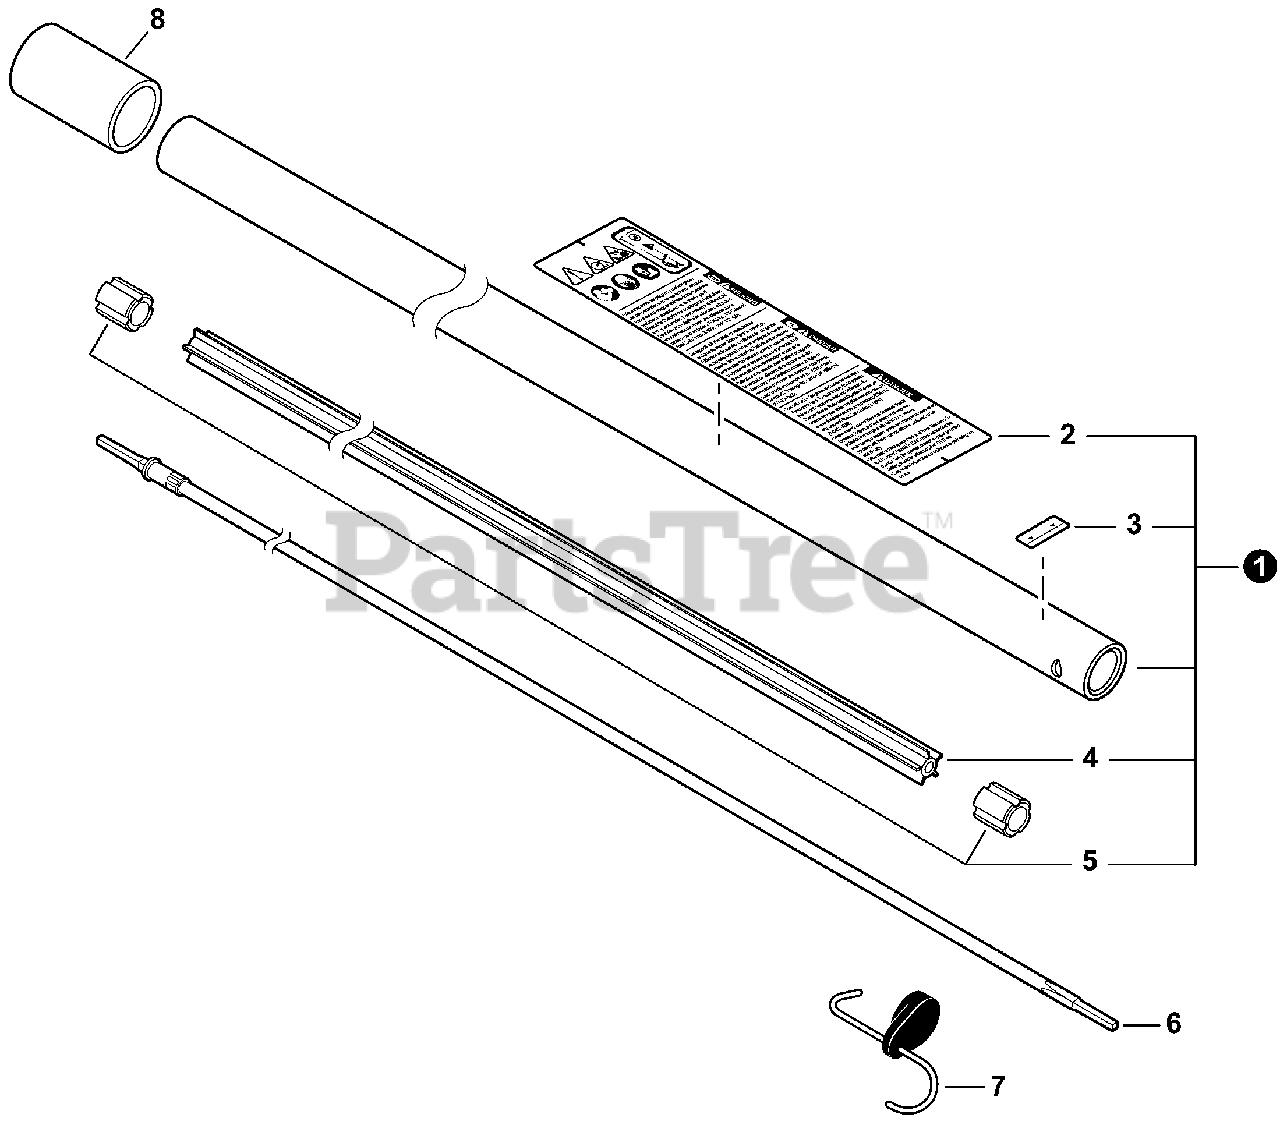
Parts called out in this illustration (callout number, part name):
1	MAIN PIPE ASSY
2	LABEL, CAUTION
3	LABEL - ALIGNMENT
4	LINER - FLEXIBLE
6	DRIVESHAFT - FLEXIBLE
7	HANGER, ATTACHMENT
8	PROTECTOR, MAIN PIPE 25 MM
